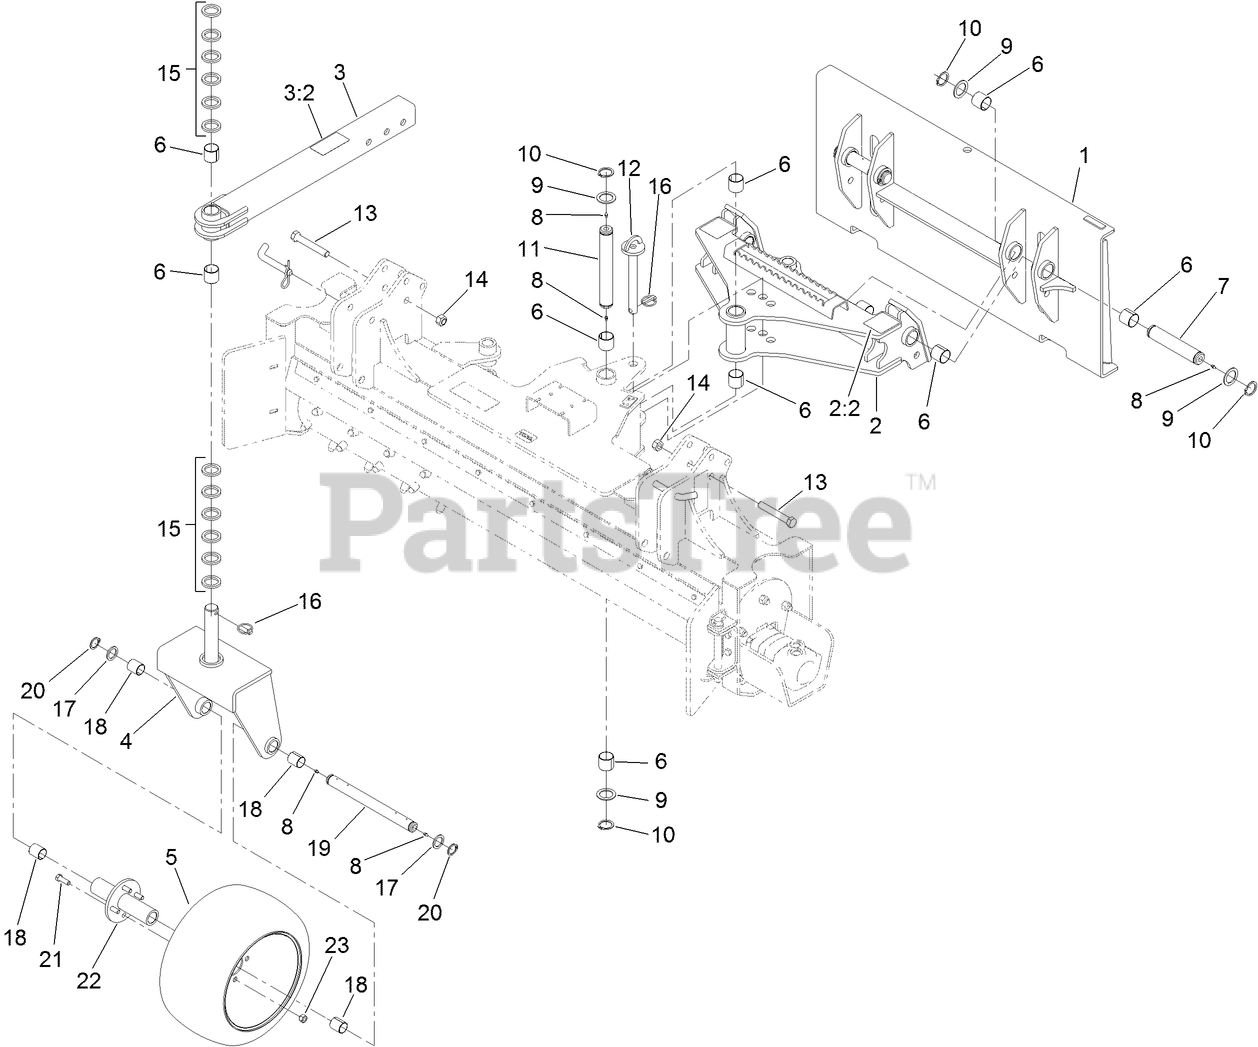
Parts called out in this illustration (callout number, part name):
1	QTACH-POWER RAKE
2	A-FRAME ASM
2:2	DECAL-WARNING
3	CASTER ARM ASM
3:2	DECAL-WARNING, PINCH POINT
4	FORK-CASTER
5	CASTER WHEEL ASM
6	BUSHING
7	PIN-PIVOT
8	FITTING-ZERK
9	WASHER
10	RING-SNAP, EXTERNAL
11	PIN-HINGE
12	PIN-ANGLE
13	SCREW-HH
14	NUT-LOCK
15	SPACER
16	PIN-LYNCH
17	WASHER-STEERING
18	BUSHING
19	PIN-CASTER
20	RING-RETAINING, EXTERNAL
22	HUB-CASTER
23	NUT-LUG
